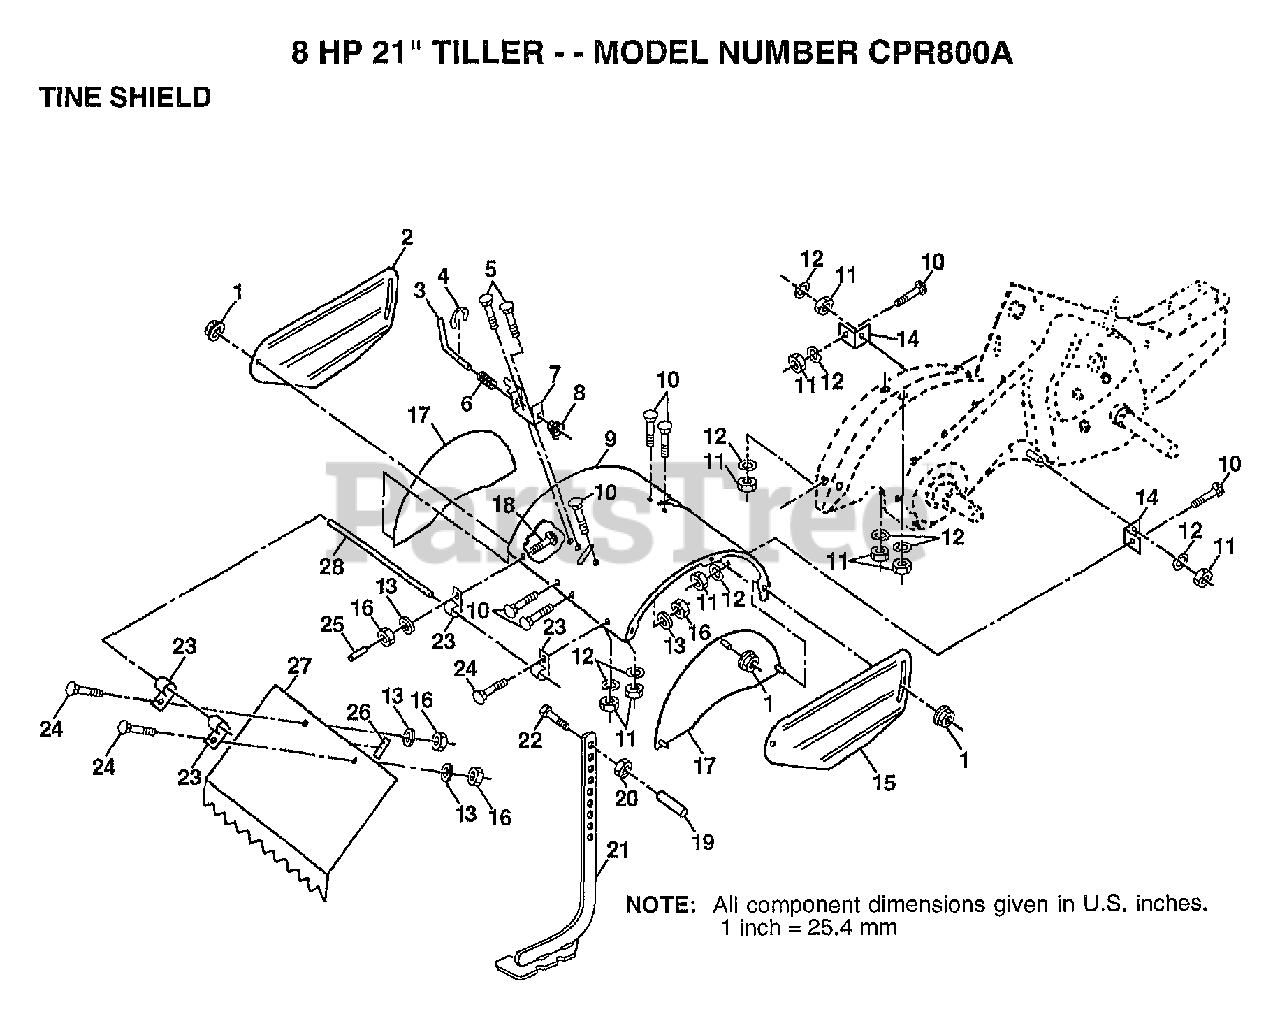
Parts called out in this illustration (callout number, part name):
1	NUT
2	SHIELD.SIDE.OUT.L
3	STAKE PIN TI
4	KLIP RING TI
5	BOLT
6	SPRING TI
7	LATCH BRACKET TI
8	SPRING CRT
9	SHIELD.TINE.GREY
10	BOLT
11	NUT.HEX.5/16-18
12	LOCKWASHER
13	LOCKWASHER
14	TINE SHLD BRKT TI
15	SHIELD.SIDE.OUT.R
17	SHIELD.SIDE.GREY
18	BOLT
19	GRIP TI
20	NUT.HEX.3/8-16UNC
21	STAKE.ASM.DEPTH
23	HINGE CRT
24	BOLT.1/4-20X1/2
25	VINYL CAP TI
26	PAD IDLER TI
27	SHIELD.LEVEL.GREY
28	PIN.HINGE
